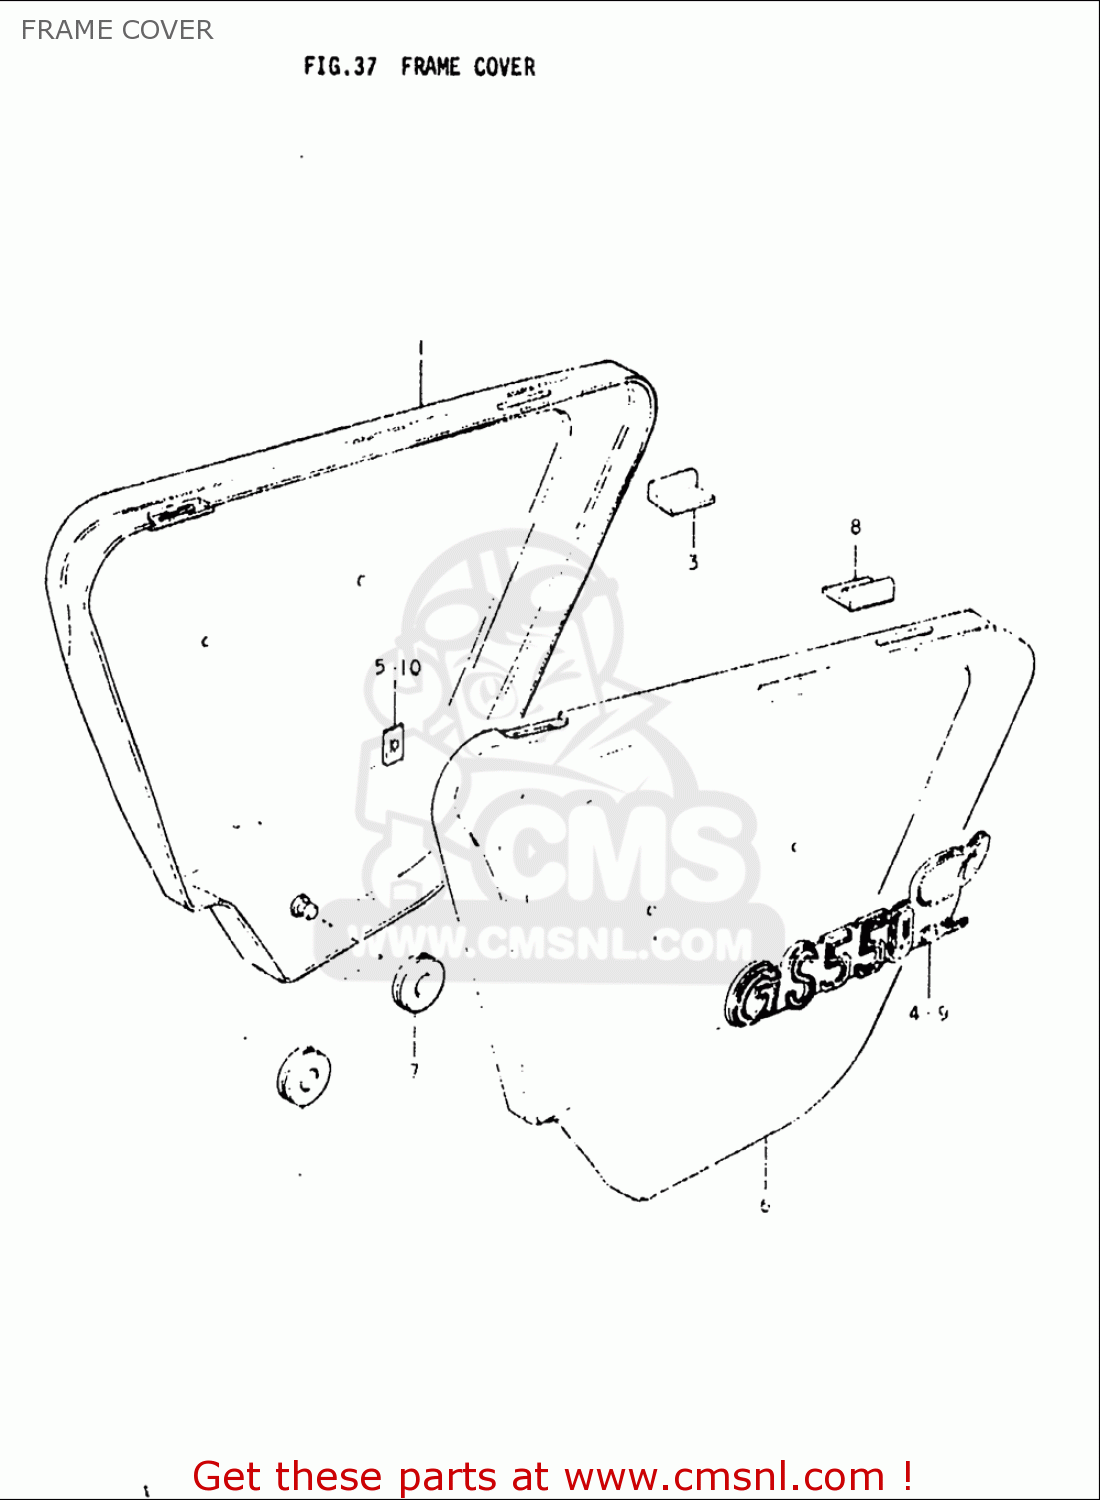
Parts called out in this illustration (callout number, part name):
1	COVER,FRAME,R
2	CUSHION
3	CUSHION,FRAME COVER
4	EMBLEM,FRAME COVER
5	NUT
6	COVER,FRAME SIDE,L
7	CUSHION
8	CUSHION,FRAME COVER
9	EMBLEM,FRAME COVER
10	NUT
